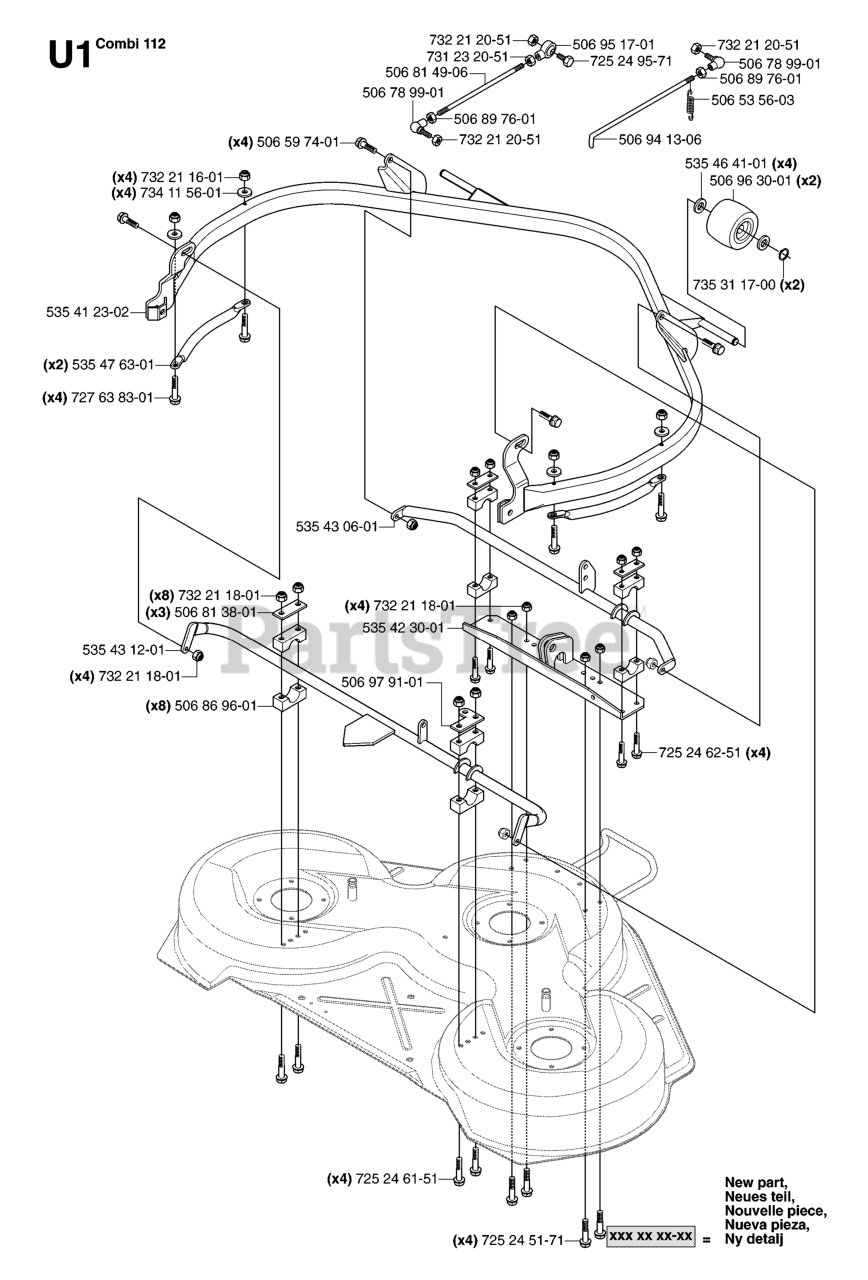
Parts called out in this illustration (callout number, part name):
2	RP BOLT 5/16-18 X3/4 ZN/YEL GR
3	BRKT ASM SWAY BAR
4	BRKT DECK SW BAR
5	RETAINER-SPRNG RB
6	REAR SUSP ARM
8	BLADE BOLT
9	LOCKWASHER
10	WASHER.BLADE
11	BLADE.42".MULCH
12	BEARING.BALL.#6204.(MANDREL)
13	SHAFT ASM VENT
14	HOUSING.MANDREL.VENTED (MACHD)
16	STRIPPER
17	BOLT CARRIAGE
18	BOLT
19	BOLT SHD 5/16-18
20	BAFFLE.VORTEX
21	LOCKNUT
22	STIFFENER BRACKET
23	DEFLECTOR BRACKET
24	CAP-SLEEVE LT
25	SPRING TORSION
26	NUT PUSH M
27	SHIELD.DEFLECTOR.MOWER.42".BLK
28	Washer 11/32 x 5/8 x 16 Ga SD
29	ROD.HINGE
30	SCREW THDROL ROLLING WASHER HD
31	WASHER
32	PULLEY/MANDREL
33	NUT
35	FASTENER.XMAS.TREE
36	FLAT IDLER PULLEY
37	WASHER
38	IDLER SPRING SPACER
44	GUARD MANDREL LH BLACK
46	SCREW.1/4-20X5/8
54	HARDENED WASHER
55	IDLER ARM
56	SPACER RETAINER
59	GUARD, BELT
61	SPRING EXTENSION
68	V-BELT TRIPATH
84	KEEPER.BELT.IDLER
90	BOLT
91	BRACKET LH (A)
92	NUT
93	Washer 1 17/32 X 7/8 X 16 Ga
94	NOSE ROLLER
95	BRACKET RH (B)
101	COVER MULCH 42"
102	SCREW
104	LOCKWASHER #10
105	LATCH ASSY
106	WELDNUT
116	BOLT, SHOULDER
117	WHEEL GAGE DONUT
118	LOCKNUT
119	WASHER.5/16.FLAT.STE.STD.
125	Pin Cotter 1/4 x 1 Plated
128	WASHER FELT
129	WASHER
131	BOLT D
132	Washer 13/32 x 1-3/8 x 13 Ga.
134	RIVET.PIN.HEAD.YELLOW.
135	BRACKET ASSY
136	BAR.ADJUST.WHEEL.ANTI.SCALP.BL
137	BOLT.CARR.5/16-18X5/8.SHORT
138	GAUGE WHEEL BRACKET ASSY
139	BRACKET.WHEEL.GAUGE.FRONT.42
140	BRKT.ASM.WHL.GA.FRONT.LH
